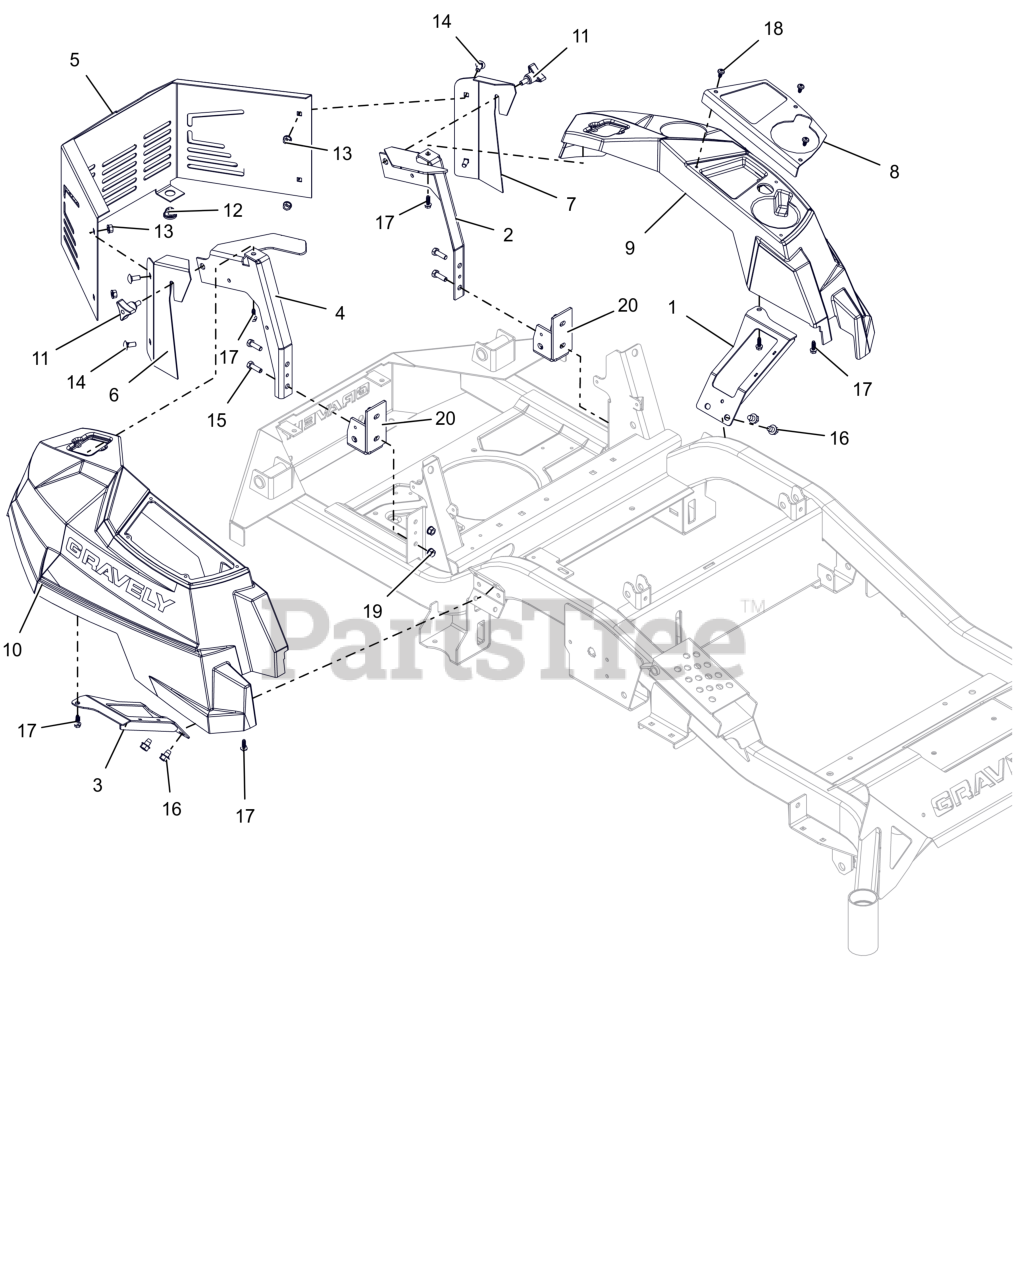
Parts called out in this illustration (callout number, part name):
1	WLDMT, LH FENDER MOUNT
2	BRKT, LH FENDER MTG
3	WLDMT, RH FENDER MOUNT
4	BRKT, RH FENDER MTG
5	GUARD, HD ENGINE
6	TRIM, HOOD STYLE (RIGHT)
7	TRIM, HOOD STYLE (LEFT)
8	PANEL, HD
9	KIT, FENDER W/FUEL DECAL-HD
10	FENDER, RH HD (2017) SHRT BOSS
11	KNOB,WING STUD 5/16-18 X .75
12	GROMMET, 10MM BOLLHOFF
13	NUT-LK-TOP-FLG .312-18 GF ZCC
14	BLT, RHSSN.31-18X.750 G5 ZCC
15	BLT, HEX .31-18X1.00 G8 ZCC
16	SCR,TAP .375-16X.50 HWH TR ZCC
17	SCR, PLASTITE-HWH 0.25 X 0.75 ZC120
18	SCR-PAN .25-15X.50 6L H/LZB500
19	NUT,LK-CTR-FLG .31-18 GF ZCC
20	BRKT, ROPS SUPPORT
